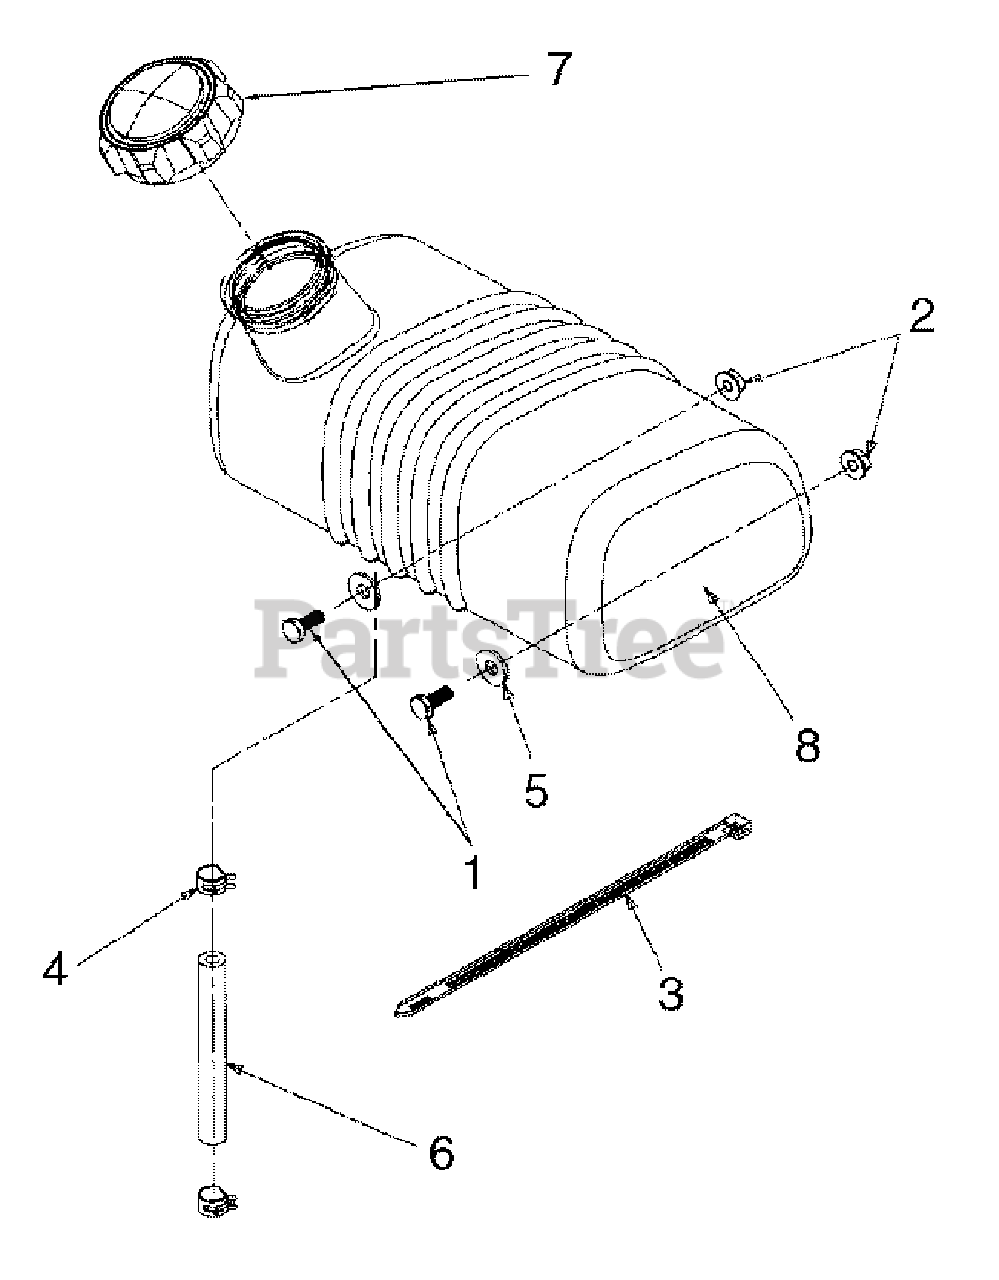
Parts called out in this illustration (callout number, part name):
1	Screw, Hex Cap, 1/4-20 x .625
2	Nut, Hex Flange Lock, 1/4-20
3	Cable Tie, 30.66 Lg
4	Clamp, Hose, 1/2 Inch
5	Washer, Flat, .28 x .74 x .063
6	Hose, Fuel Line 9 Inch
7	Cap, Fuel
8	Tank, Fuel
